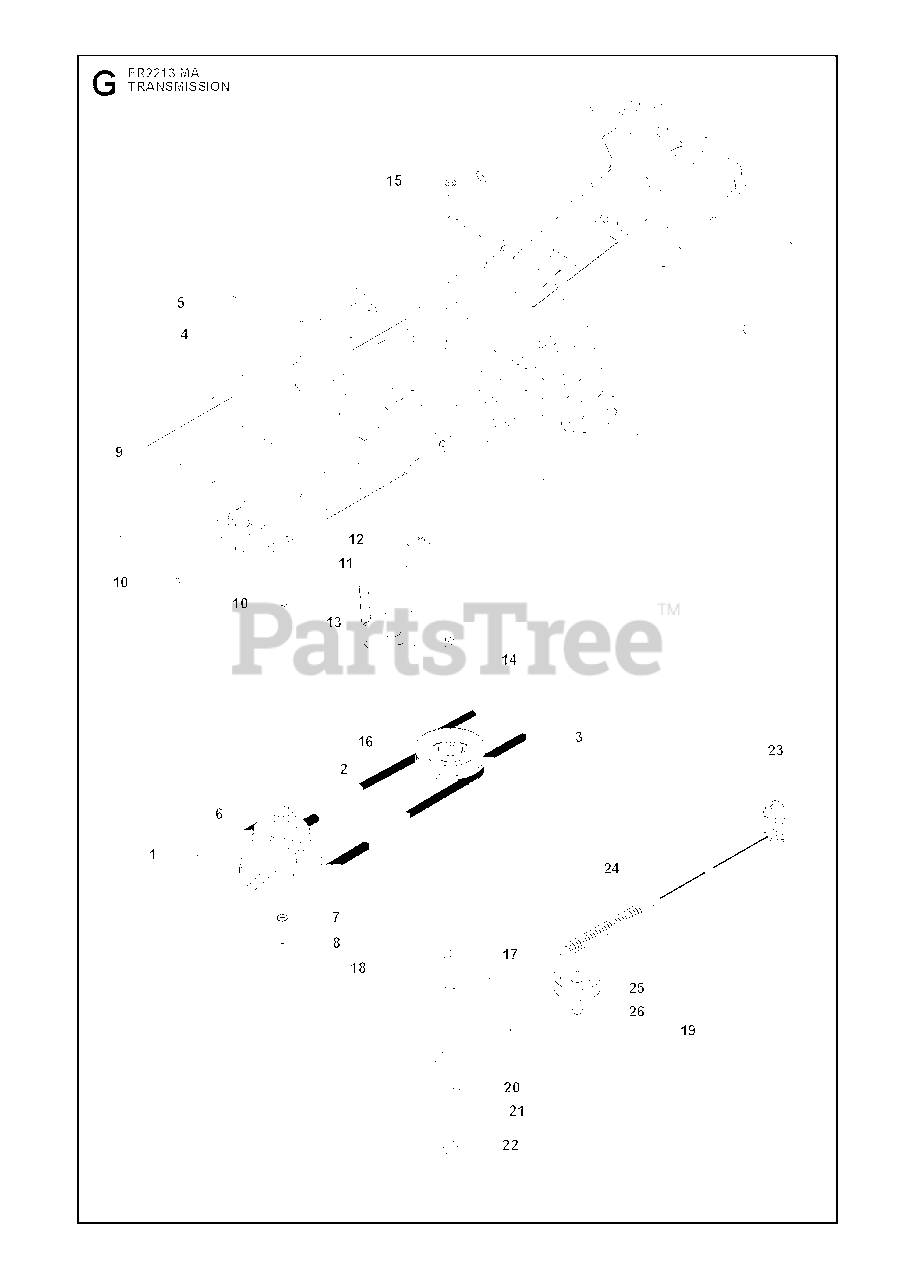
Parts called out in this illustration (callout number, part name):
2	BELT
9	BELT GUIDE
11	TENSIONER
12	RETAINING RING SGA 25
14	SHAFT
18	BELT GUIDE
22	BOLT
